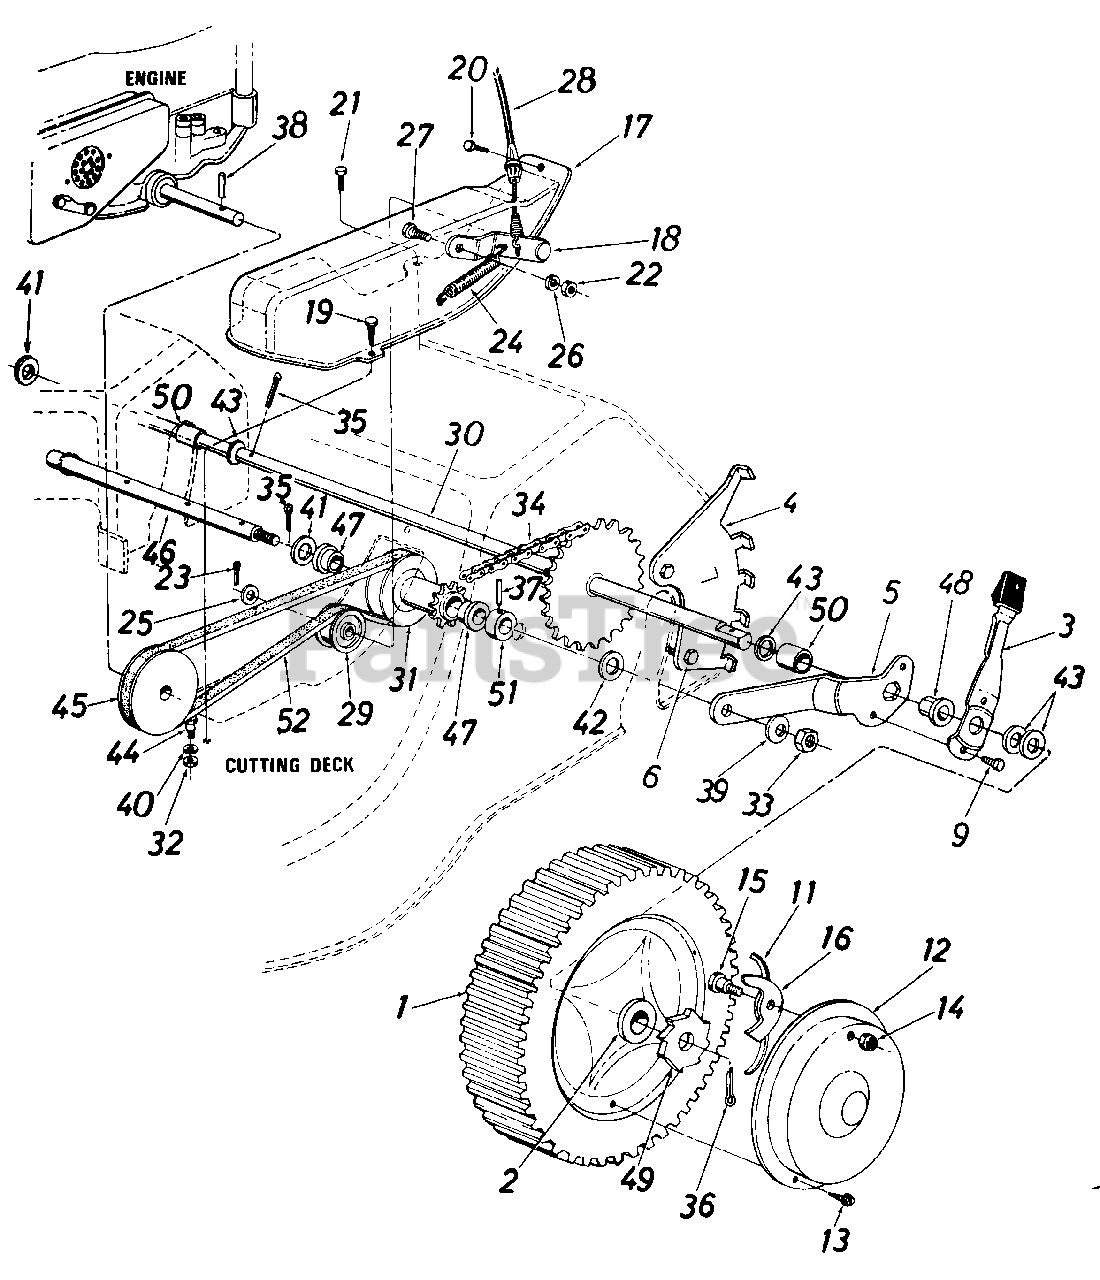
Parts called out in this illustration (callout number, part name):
1	Rear Wheel Ass'y. Comp.
2	Flange Brg. 1/2" I.D.
3	Spring Lever w/Knob
4	Index Plate-L.H.
5	Pivot Brkt.-L.H.
6	Hex Wash. Hd. Tap Scr. 1/4 x 62n Lg.
9	Hex B-Tap Scr. 1/4 x .38" Lg.
11	Nylon Spring
12	Hub Cap
13	Pan Hd. Tap Scr. #12 x .50"
14	Hex Ins. L-Nut 1/4-20 Thd.
15	Shld. Bolt .342" Dia. x .268
16	Pawl
17	456/N Belt Cover
18	Idler Bracket Ass'y.
19	Hex Wash. Hd. Self-Tap Scr. 1/4-20 x .50" Lg.
20	Hex Drilling Scr. #10 x .50"
21	Hex TT-Tap Scr. 1/4-20 x .75"
22	Hex Nut 1/4-20 Thd.
23	Cotter Pin 1/8" Dia. x 1"
24	Extension Spring 1.12" Lg.
25	Fl-Wash. .531" I.D. x .930"
26	L-Wash. 1/4" I.D.
27	Shld. Bolt .375" Dia. x .181
28	Clutch Cable-50"
29	Flat Idler-Plastic
30	Rear Shaft Ass'y.
31	Pulley w/9 Tooth Sprocket Ass'y.
32	Hex Nut 5/16-18 Thd.
33	Hex Jam Nut 3/8-16 Thd.
34	#48 Chain 1/2" Pitch x 31 Links
35	Cotter Pin 3/32" Dia. x 1."
36	Cotter Pin 1/8" Dia. x 1"
37	Spring Pin Spir. 3/16" Dia. x 1.00" Lg.
38	Spring Pin Spir. 3/16" Dia. x 1.50" Lg.
39	Bell-Wash. .400" I.D. x .88"
40	L-Wash. 5/16" I.D.
41	Fl-Wash. .531" I.D. x .930"
42	Bell-Wash. .400" I.D. x 1.13n
43	Fl-Wash. .510" I.D. x 1.0" O.D.
44	Shld. Bolt .437" Dia. x .350"
45	Engine Pulley
46	Pulley Shaft 9.18" Lg.
47	Flange Brg. .506" I.D. Plastic
48	Hex Flange Brg. x .506" I.D. Plastic
49	Rachet
50	Spacer .765" I.D. x .960" Lg.
51	Spacer. 505" I.D. x .44" Lg.
52	"V"-Belt 1/2 " x 31 " Lg.
